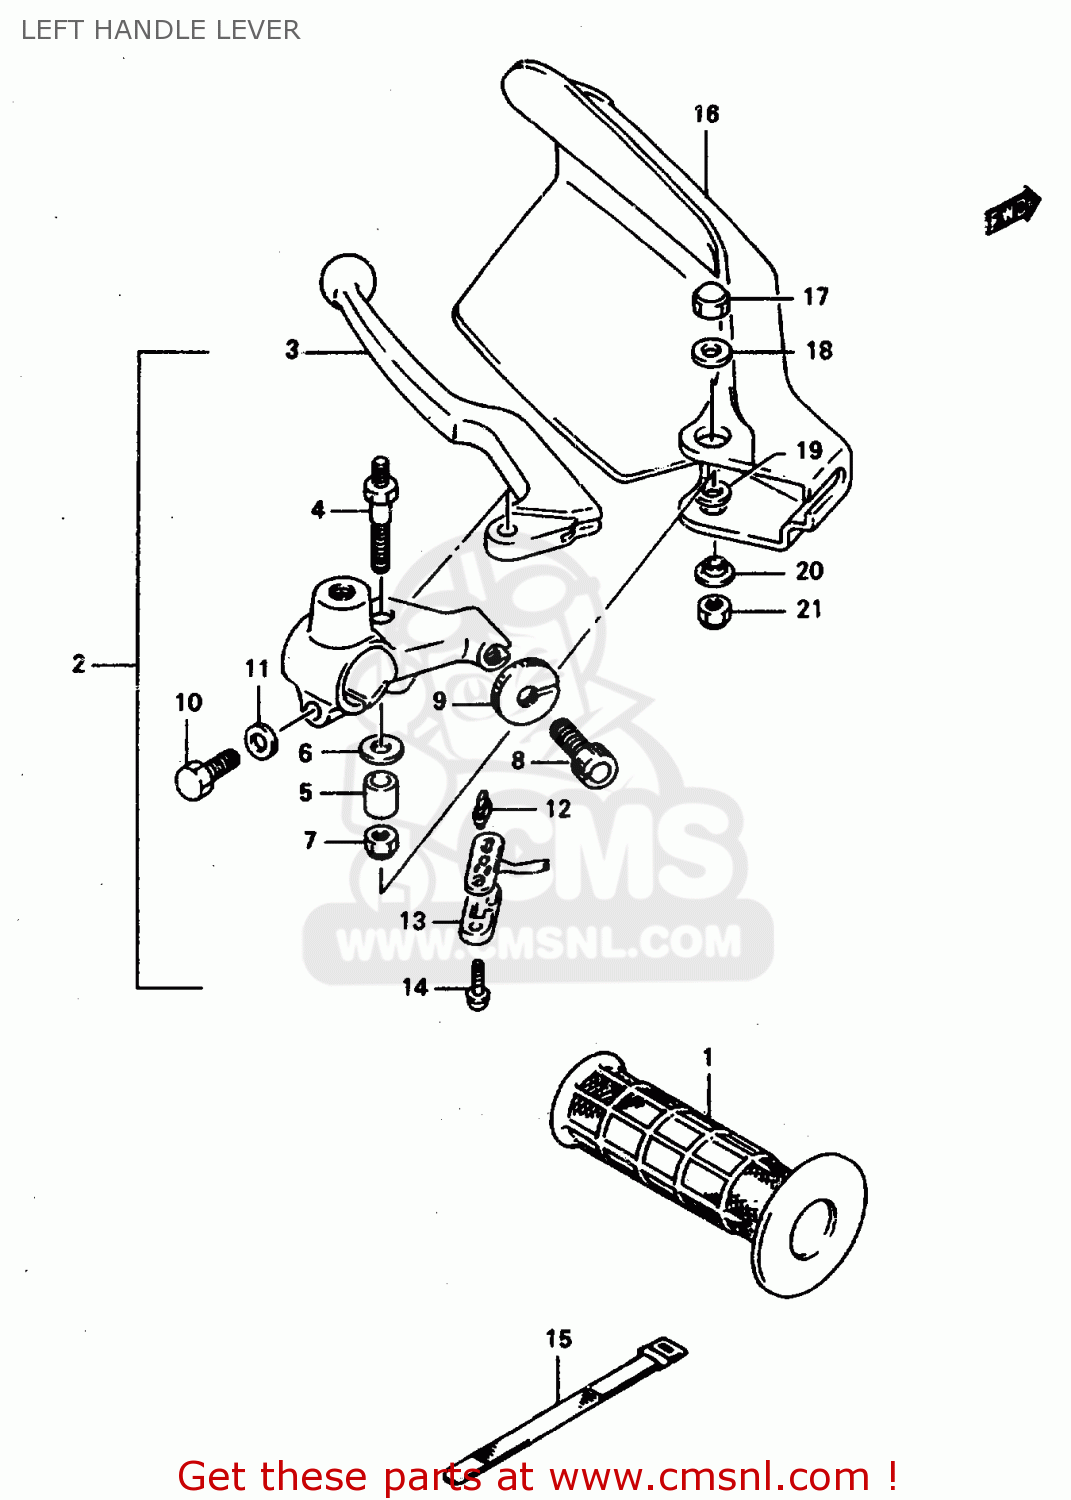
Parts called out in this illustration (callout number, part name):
1	GRIP,L
2	LEVER ASSY,CLUTCH
3	LEVER,CLUTCH
4	BOLT,LEVER SET
5	SPACER,LEVER SET
6	WASHER,LEVER SET
7	NUT
8	ADJUSTER,CABLE
9	NUT,LOCK
10	BOLT
11	WASHER
12	CONTACT,SWITCH
13	COVER,FR BK TERMINAL BASE
14	SCREW
15	CLAMP(L:120)
16	COVER,KNUCKLE,LEFT
17	NUT
18	WASHER(6.5X20X1.6)
19	WASHER(6.5X16X1.2)
20	WASHER
21	NUT 6MM
